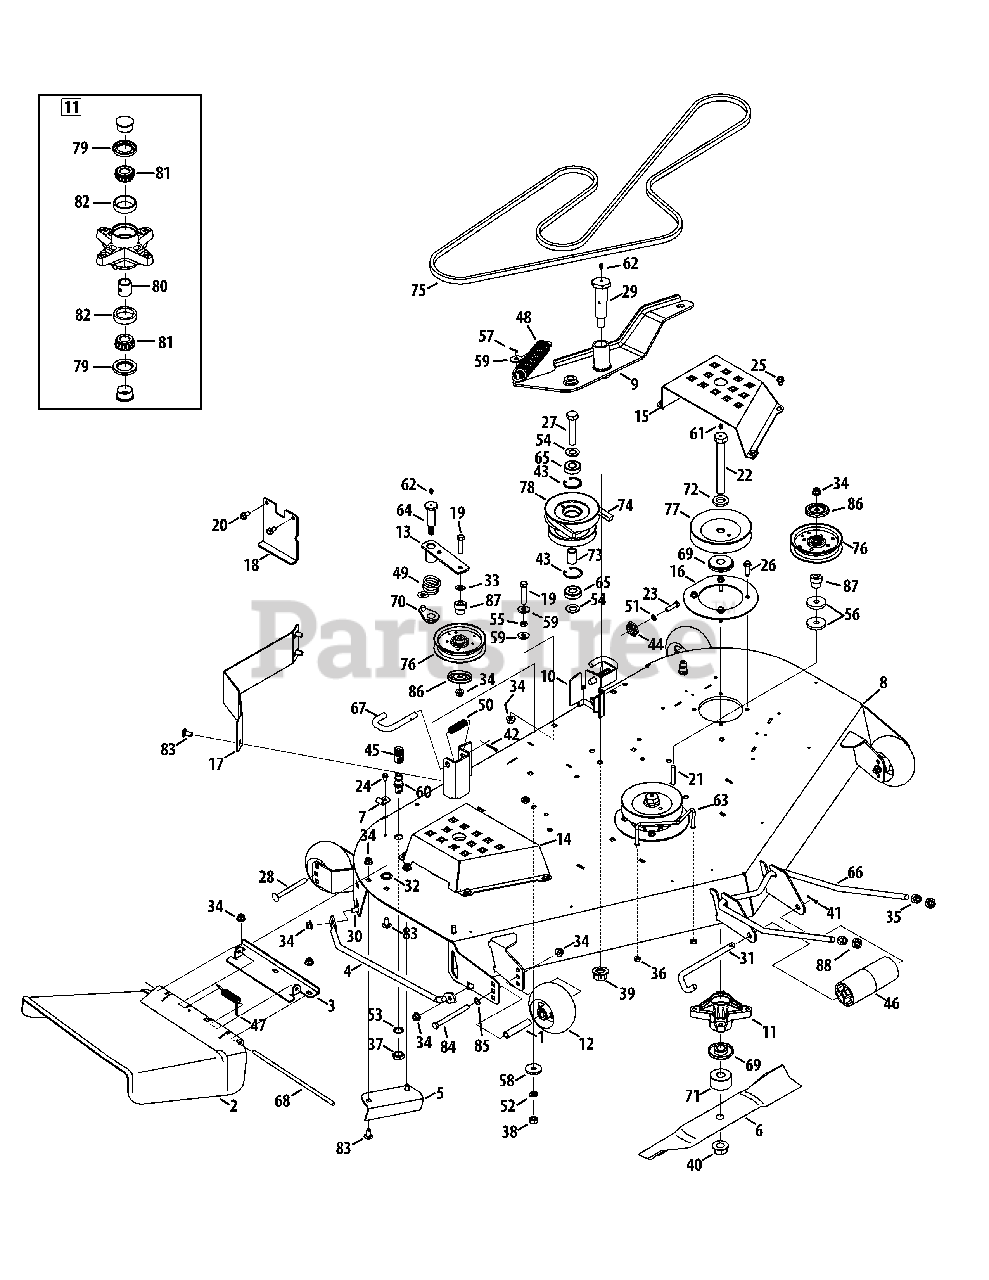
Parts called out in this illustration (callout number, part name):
1	Spacer, .390 x .620 x 3.04
2	Chute Deflector
3	Chute Deflector Bracket
4	Finger Guard
5	Micor Chute Baffle
6	Hi-Lift Blade, 19
7	Hook Retainer Bracket
10	Hanger Adjustment Bracket
11	Spindle Assembly
12	Wheel, 5.0
16	Spindle Reinforcement Plate
17	Baffle
18	Up-Stop Bracket
19	Hex Screw, 3/8 x 16 x 1.75
20	Hex Washer Screw, 5/16-18 x .750
21	Carriage Bolt, 3/8-16 x 2.50
22	Hex Screw, 3/4-16 x 6.00
23	Hex Screw, 5/16-18 x 1.25
24	Hex Washer Screw, 1/4-20 x .500
25	Hex Washer Screw, 5/16-18 x .625
26	Hex Washer Screw, 5/16-18 x 1.50
27	Hex Screw, 5/8-18 x 3.00
28	Carriage Screw, 3/8-16 x 4.00
29	Shoulder Screw, 1.0 x 3.00
30	Carriage Bolt, 3/8-16 x 1.00
31	Roller Pin, 1/2 x 7.31
32	Push Nut, 3/8
33	Flat Washer, .375 x .738 x .063
34	Flange Lock Nut, 3/8-16
35	Flex Lock Nut, 1/2-13
36	Hex Lock Nut, 1/4-20
37	Hex Nut, M16-1.5
38	Hex Nut, 7/16-14
39	Flange Lock Nut, 5/8-18
40	Flange Lock Nut, 3/4-16
41	Cotter Pin, 3/32 x 1.25
42	Cotter Pin, 5/32 x 1.25
43	Retainer Ring
44	Deck Adjustment Gear
45	Water Nozzle Adapter
46	Front Roller
47	Torsion Spring, 180 x .639 x 2.16 x .12
48	Extension Spring, 1.25 x 6.9
49	Idler Torsion Spring, 1.10 x 1.3
50	Compression Spring, .66 x 1.8
51	Lock Washer, 5/16
52	Lock Washer, 7/16
53	Lock Washer, 5/8
54	Flat Washer, .650 x 1.250 x .075
55	Jam Nut, 3/8-16
56	Flat Washer, .4375 x 1.75 x .25
57	Cotter Pin, 3/32 x .750
58	Flat Washer, .45 x 1.5 x .172
59	Falt Washer, .385 x 1.00 x .135
60	Deck Water Nozzle
61	Grease Fitting, 1/4-28 x 3/16
62	Drive Lube Fitting, 3/16
63	Belt Drive Guard
64	Shoulder Screw, 7/16-14 x .687 x 2.443
65	Ball Bearing, .625 x 40 x 12
66	Front Hanger Rod
67	Mower Support Pin
68	Chute Deflector Rod
69	Spindle Deck Spacer
70	Retainer Spring
71	Spindle Spacer, .760 x 2.0 x 1.10
72	Spacer, .812 x .218
73	Spacer, .88 x .635 x 1.25
76	Idler Pulley
78	Double Pulley
80	Bearing Spacer, .78 x 1.0 x 1.0425
81	Cone Bearing, .750
82	Bearing Cup, .750
83	Carriage Bolt, 3/8-16 x .75
84	Hex Screw, 3/8-16 x 4.00
85	Washer, .375 x .700 x .030
86	Pulley Cap
87	Shoulder Spacer, Idler
88	Nut, Jam, 1/2-13
